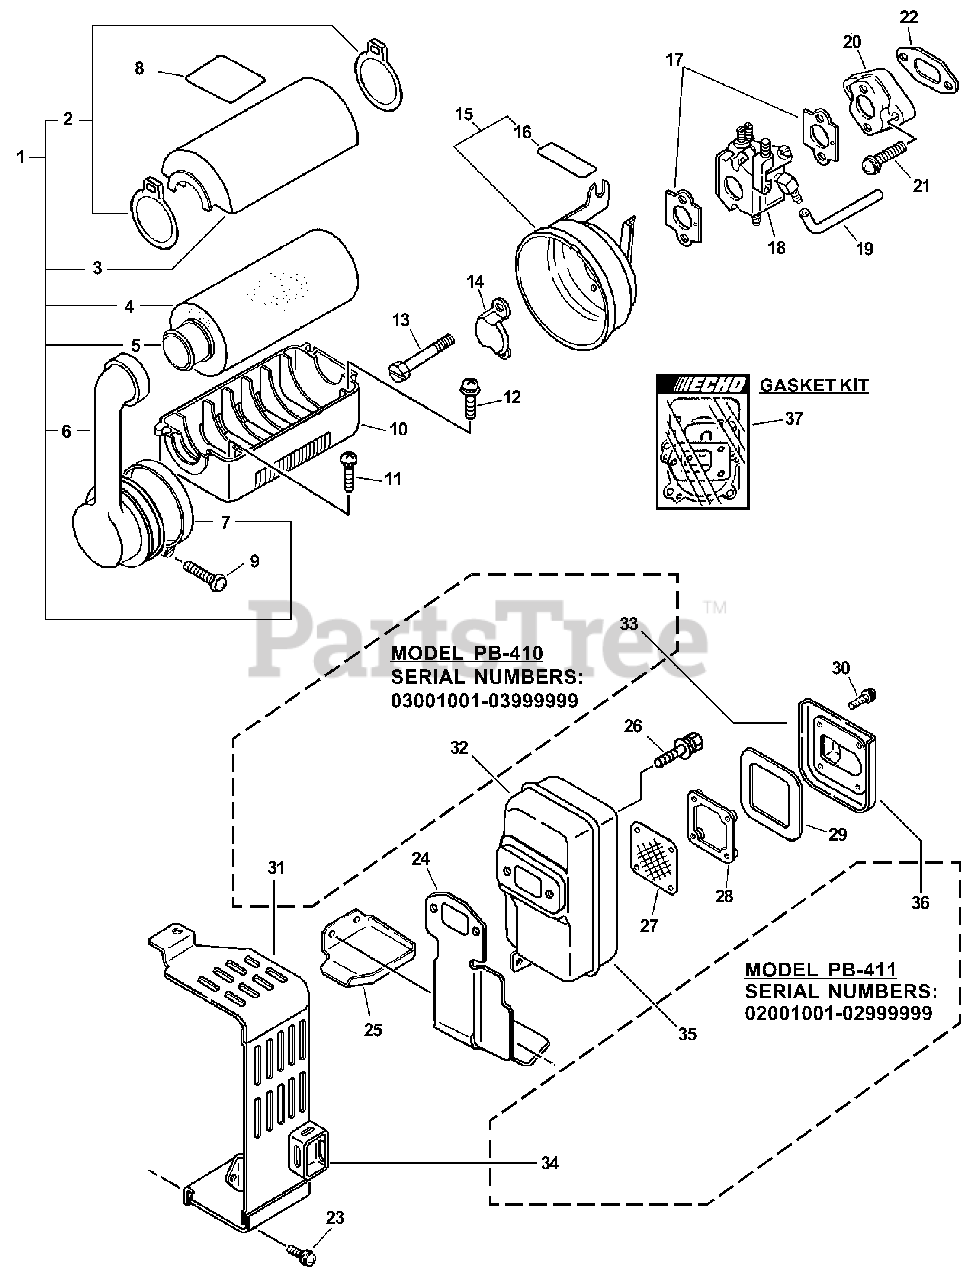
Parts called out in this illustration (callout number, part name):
1	AIR FILTER ASSY
3	COVER, AIR FILTER
4	FILTER, AIR
5	HOLDER, AIR FILTER
6	ADAPTER, INTAKE
8	LABEL - CAUTION
9	SCREW 5×30
10	CASE, AIR FILTER
11	SCREW 6×15
12	SCREW 6×20
13	SCREW 5×50
14	PLATE, PREVENT
15	CASE, AIR FILTER
16	LABEL - CHOKE
17	GASKET, CARBURETOR
18	CARBURETOR - WT-410C
19	PIPE
20	INSULATOR
21	SCREW 6×25
22	GASKET, INTAKE
23	SCREW 5×14
24	GASKET, EXHAUST
25	BRACKET, MUFFLER COVER
26	BOLT 6×20
27	SCREEN KIT
28	SEAT, SCREEN
29	GASKET, EXHAUST
30	SCREW 4×16
31	COVER, MUFFLER
33	GUIDE, EXHAUST
34	COVER, MUFFLER
35	MUFFLER
36	GUIDE, EXHAUST
37	GASKET KIT
